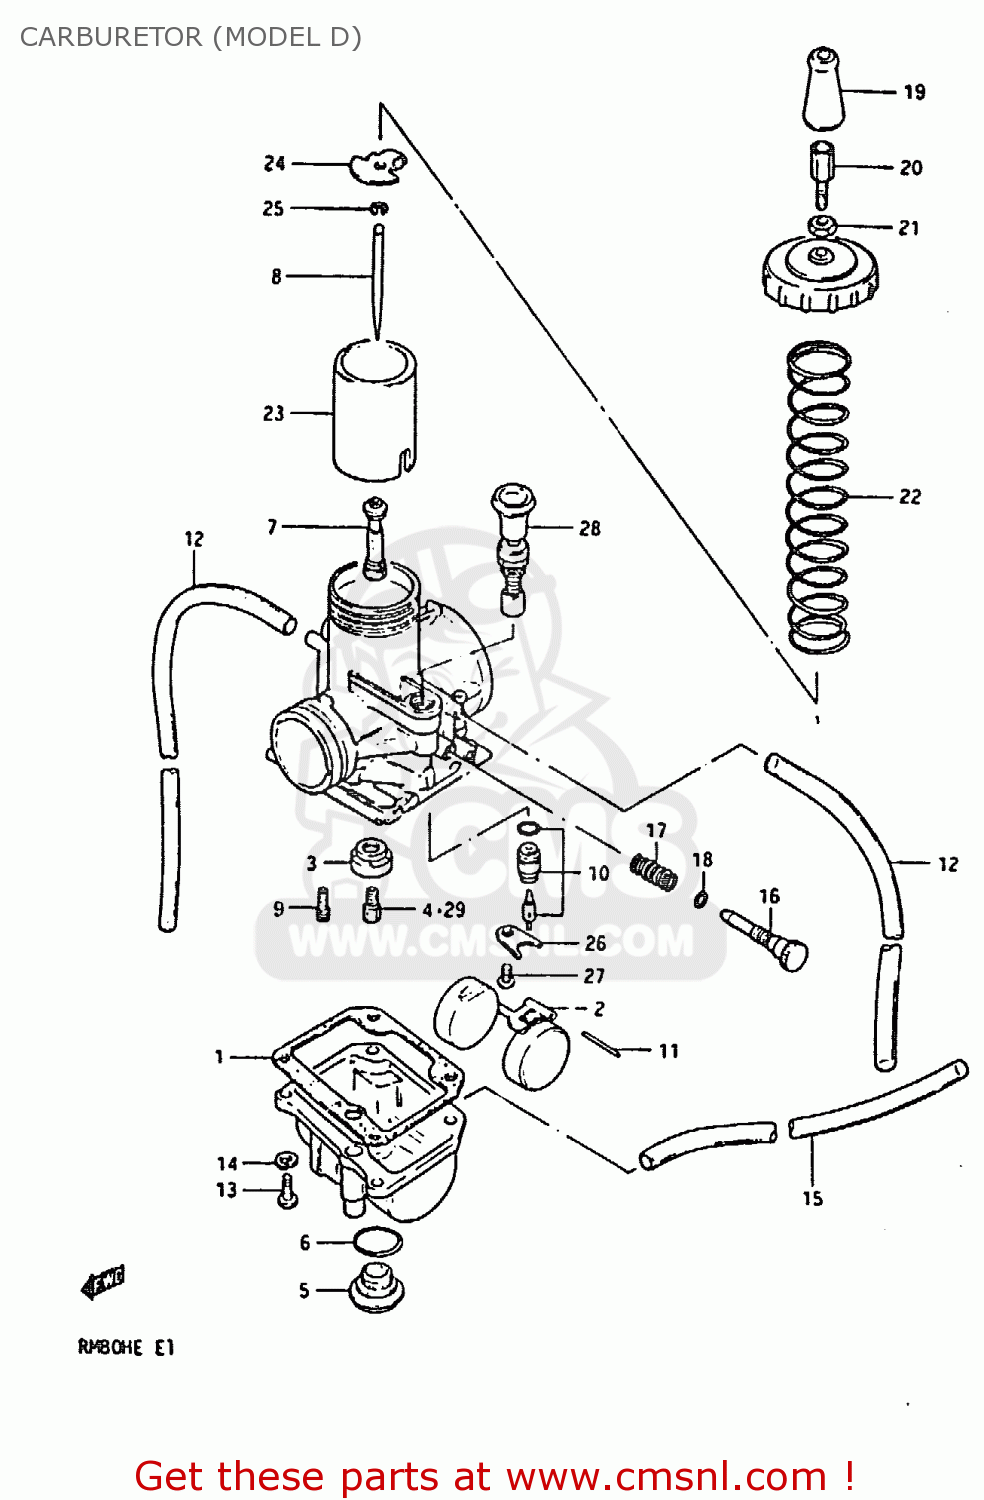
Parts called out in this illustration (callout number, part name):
1	GASKET,FLOAT CHAMBER (NAS)
2	FLOAT
3	RING
4	JET
5	PLUG
6	O RING
7	JET,NEEDLE
8	NEEDLE,JET
9	JET
10	VALVE ASSEMBLY,NEEDLE
11	PIN,FLOAT
12	HOSE
13	SCREW
14	LOCK WASHER
15	HOSE
16	ADJUSTER
17	SPRING
18	O RING
19	CAP,RUBBER
20	ADJUSTER,CABLE
21	NUT
22	SPRING,THROTTLE VALVE
23	VALVE,THROTTLE
24	PLATE,THROTTLE VALVE
25	CLIP
26	PLATE
27	SCREW
28	VALVE ASSEMBLY,STARTER
29	JET
